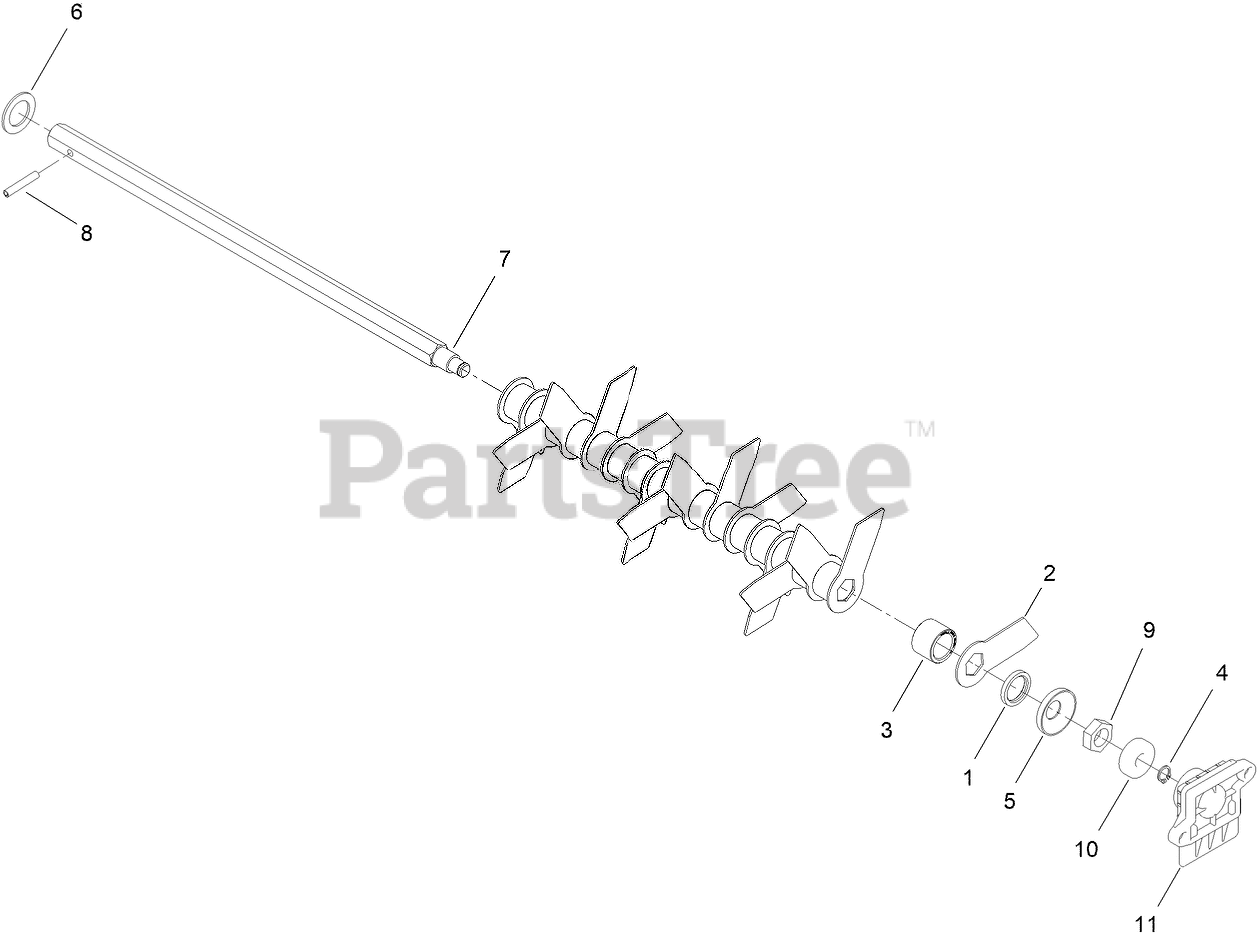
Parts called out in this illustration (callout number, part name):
1	SPACER
2	BLADE-SCARIFIER
3	SPACER
4	CIRCLIP
5	SHOULDER PIECE
6	WASHER
7	ROD-HEX
8	PIN-DOWEL
9	NUT M16 PLAIN RAW
10	BEARING
11	BEARING HOUSING
